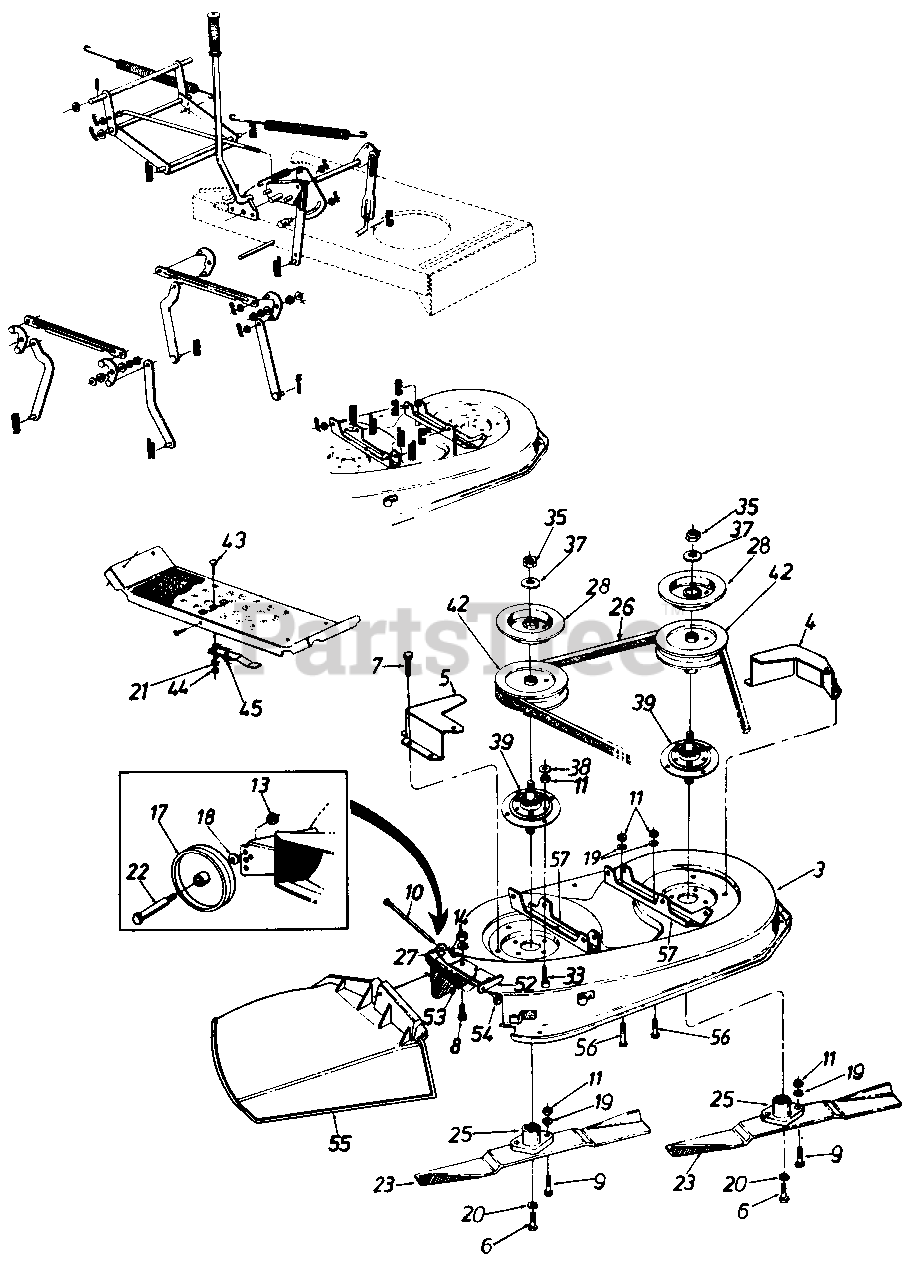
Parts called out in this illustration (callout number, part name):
3	42" Deck Ass'y.
6	Hex Bolt 3/8-24 x l.O" Lg.
7	Hex Wash. Hd. TT-Tap Scr. 1/4-20 x .5" Lg.
8	Truss Mach. Scr. 1/4-20 x .75"
9	Hex Bolt Special 5/16-24 x 1.0"
10	Hinge Pin
11	Hex Nut 5/16-24 Thd.
13	Hex Top L-Nut 3/8-16 Thd.
14	Hex Nut 1/4-20 Thd.
17	DeckWheel 5"
18	Bell-Wash. .40" I.D. x .8 O.D.
19	L-Wash. 5/16" I.D.
20	L-Wash. 3/8" I.D. H.D.
21	L-Wash. 1/4" I.D.
22	Shld. Bolt .498" Dia. x 1.53"
23	High-Lift Blade
25	Blade Adapter
26	V-Ben
27	Bell-Wash. 1/4" I.D.
28	Brake Disc
33	H0x Bolt 5/16-24 x .75" Lg.
35	Hex Jarn Nut 5/8-18 Thd.
37	L-Wash. 5/8" I.D.
38	L-Wash. 5/16" I.D.
39	Blado Spindle Ass'y. Comp.
42	5.5" Dia. Pulley
43	Carr. Bolt 1/4-20 x .62"
44	Hex Nut 1/4-20 Thd.
45	Blade Brake Ass'y.
52	Hinge Mtg. Brkt.
53	Torsion Spring
54	Push Nut
55	Chute Ass'y. Comp.
56	Hex Bolt 5/16-24 x .75" Lg.
